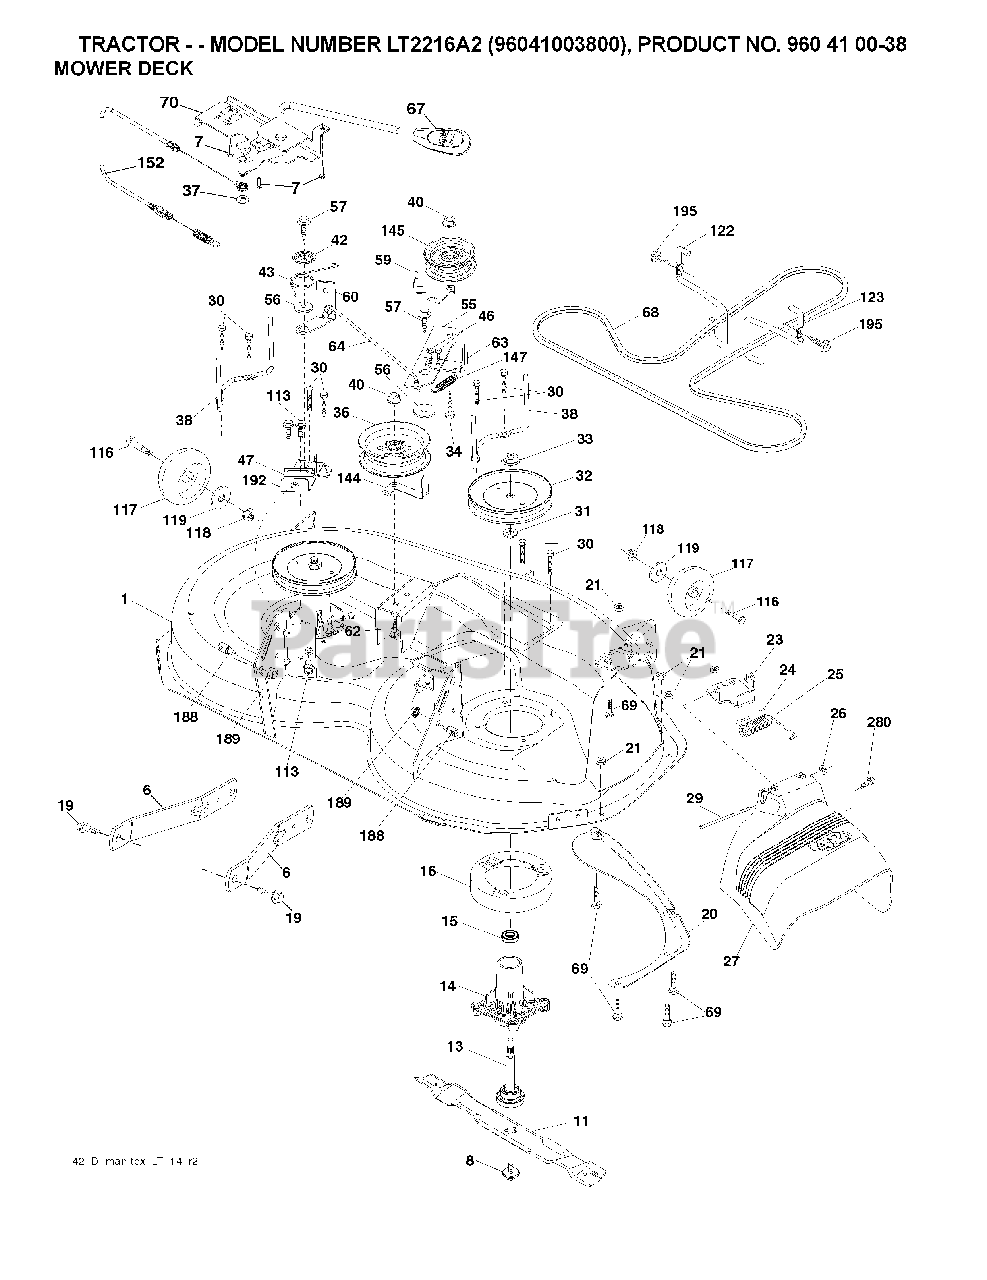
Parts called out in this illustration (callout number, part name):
1	DECK.WELDMENT.42"
6	ARM.SUSPENSION.MOWER.R
7	SCREW.#10 X 0.750.BOS THREAD
8	BOLT.WASHER.ASM.7/16-2
11	42" HI-LIFT BLADE
13	SHAFT.ASM.MDRL.N/GREASE.38
14	HOUSING MANDREL
16	STRIPPER, MWR ROUND
19	BOLT.SHOULDER
20	BAFFLE.VORTEX
21	LOCKNUT
23	BRKT.DEFLECTOR.38"2005+
24	CAP-SLEEVE LT
25	SPRING.TORSION.DEFLECT
26	NUT PUSH M
29	ROD.HINGE
30	SCREW, WASHER HEAD
31	WASHER.SPACER.MANDREL
32	PULLEY.MANDREL.5.438.PD
33	NUT.FLANGE.LOCK.TOP
34	BOLT.3/8-16X1.50
36	PULLEY.IDLER.2006
38	KEEPER.BELT.LH.MANDREL
40	NUT LOCK FLG 3/8-16 UNC
42	SPRING.TORSION.BRAKE
43	SRPING.TORSION.RETAINE
46	SCREW.1/4-20X5/8
47	BRKT.CLUTCH.CABLE
55	IDLER.ARM
56	SPACER.RETAINER
57	SCREW 3/8-16X1
59	GUARD, BELT
60	ARM BRAKE MOWER
62	BOLT
63	ARM BRAKE MOWER
64	LINK BRAKE
67	HANDLE.CLUTCH.CABLE.LT
68	BELT.DRIVE.MOWER.TEX.42"
69	BOLT
70	CLUTCH.ASM.MANUAL.LT.TEX
113	BOLT.5/16HEX.WHS.HD
117	WHEEL.GAGE.HALF.SPOKED
118	LOCKNUT
119	WASHER
122	KEEPER BELT ENGINE LH
123	KEEPER BELT RH
144	KEEPER.BELT.MOWER
145	PULLEY.IDLER.48"PRIMARY
147	RETURN SPRING
152	CLUTCH CABLE
188	STUD.FASTNER.W/ANTI-ROTATE
189	NUT LOCK HEX FLANGE 5/16-18
192	BRKT.BRAKE.STAND.LH.
195	SCREW, 3/8-16X3/4
280	SCREW 3/8-16X1/2
